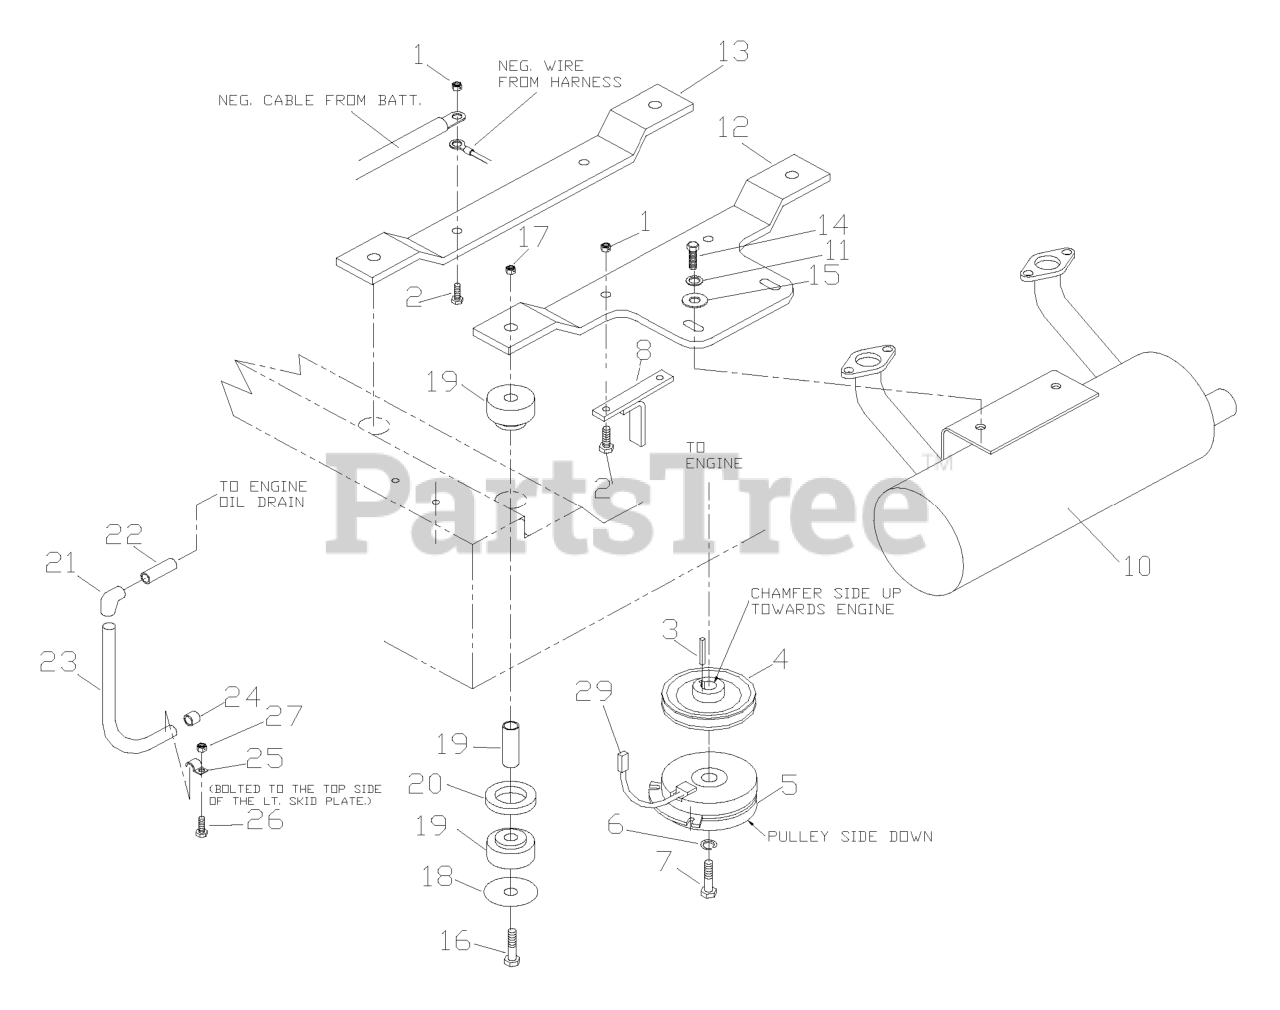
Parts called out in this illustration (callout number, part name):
1	NUT 5/16C CENTERLOCK
2	HCS 5/16C X 1 3/4
3	KEY 1/4" SQ X 1 7/8"
5	ELECTRIC CLUTCH W/CABLE
6	WASHER 7/16 LOCK
7	BOLT 7/16F X 2 1/2
8	CLUTCH TIE DOWN
9	KOH PIGTAIL
10	MUFFLER KOHLER GEN II
11	WASHER.LOCK.HVY.HLCL.SPR.5/16
12	REAR ENGINE MOUNT
13	ENGINE MOUNT
14	HCS 5/16C X 3/4
15	WASHER 5/16 FLAT
16	HCS 1/2C X 3 1/4
17	NUT 1/2-13 HEX NYLOC ZD
18	ISOLATOR WASHER
20	ISOLATOR SPACER
21	90 DEG.ELBOW 3/8NPT
22	PIPE 3/8 NPT 1-1/2
23	OIL DRAIN HOSE
26	HCS 1/4C X 3/4 HCS
27	NUT 1/4C CENTER LOCK
29	CLUTCH HARNESS
